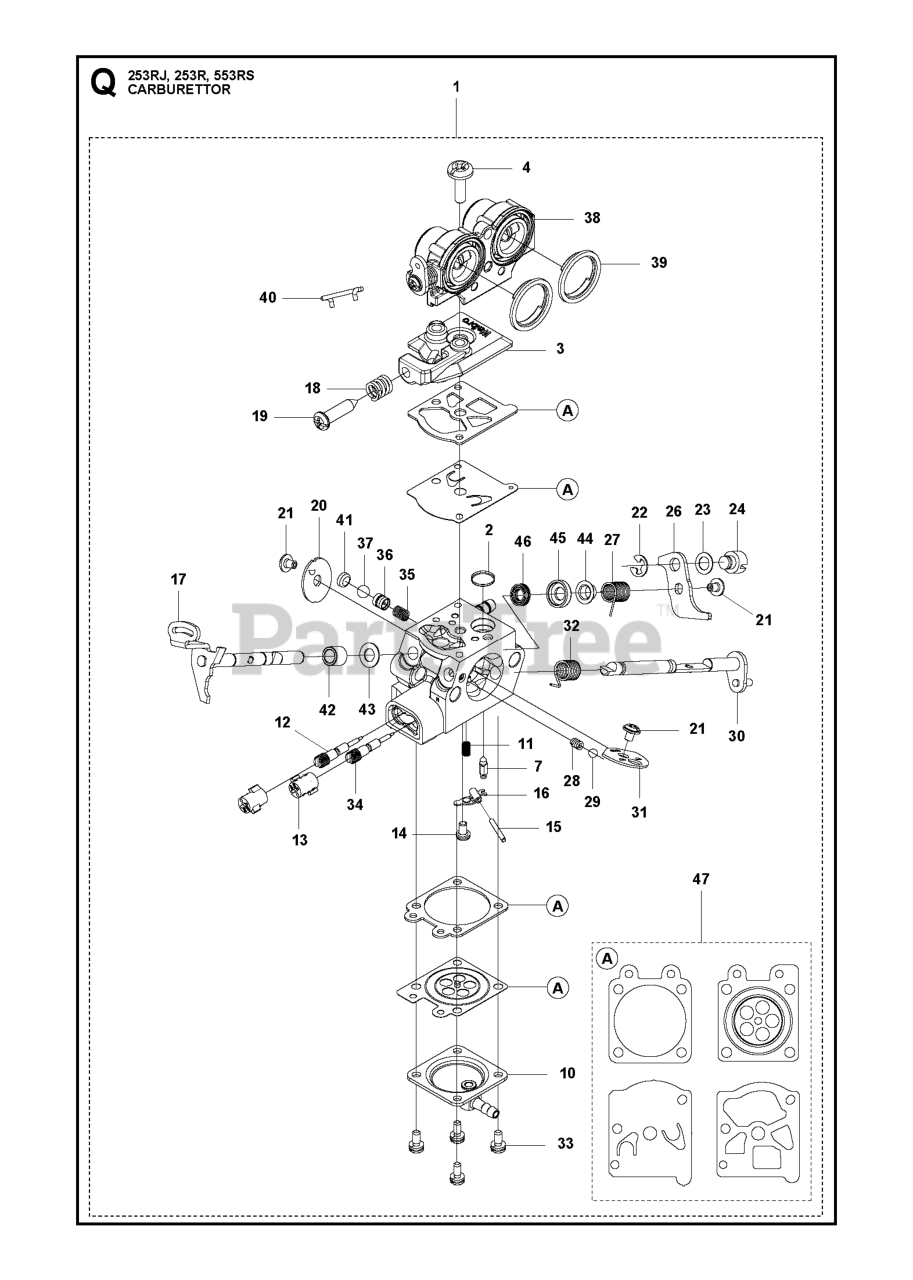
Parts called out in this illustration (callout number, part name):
2	SCREEN
7	VALVE INLET
26	LEVER, THROTTLE
30	SHAFT, CHOKE
31	ACCELATOR
33	SCREW ASSY
36	PISTON
37	BALL
47	GASKET KIT
